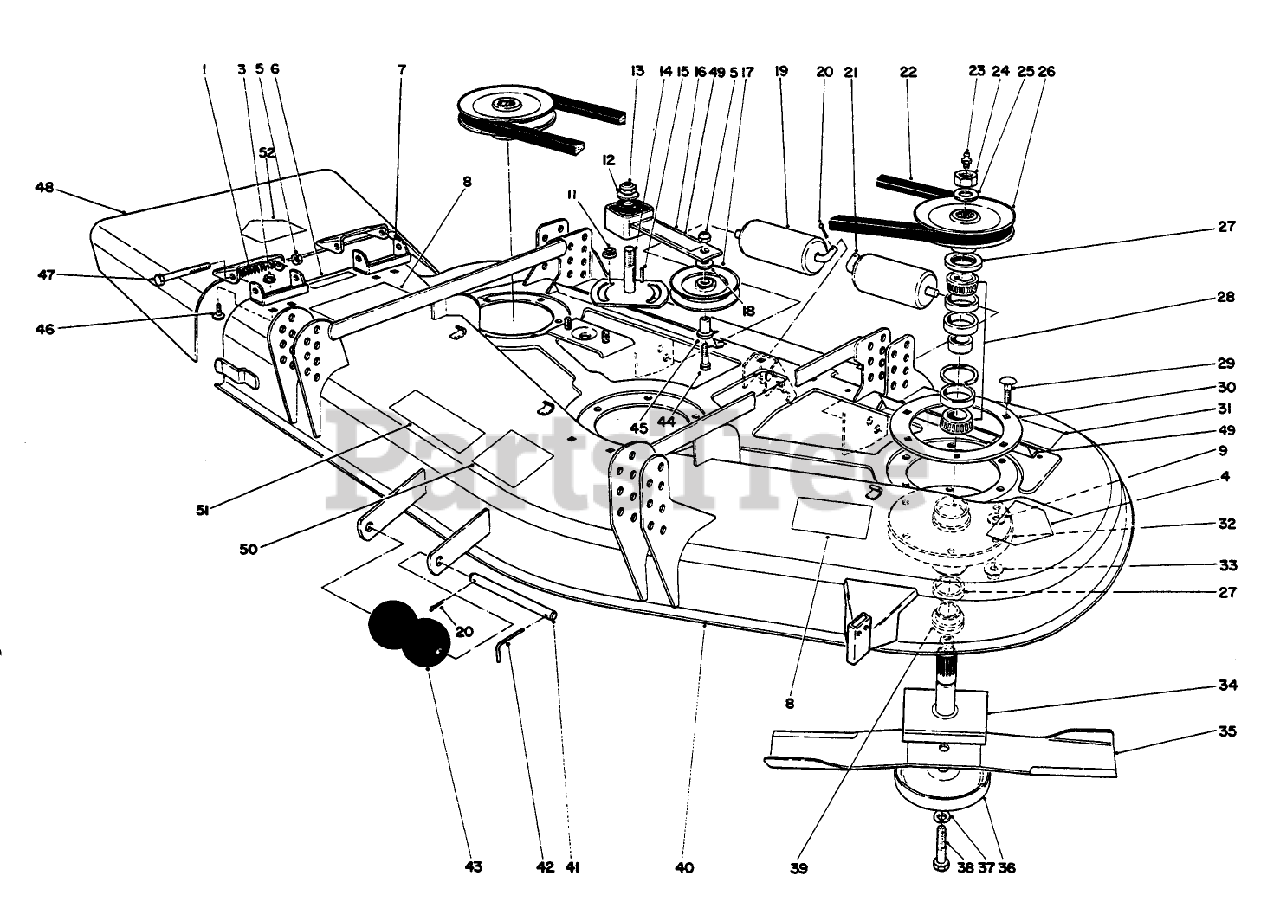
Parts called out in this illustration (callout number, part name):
1	SPRING
3	NUT-HF
4	DECAL-DANGER
5	NUT-HEX
6	DECAL-DANGER
7	Bracket-Pivot
8	DECAL-DANGER, THROWN OBJECT
9	WASHER-FLAT
11	NUT-HHF, WHIZ
12	WASHER-FLAT
13	NUT-LOCK, NI
14	PLATE-IDLER
15	KEY-SQUARE
16	IDLER ARM ASM
17	PULLEY-IDLER
18	WASHER-FLAT
19	ROLLER-DECK
20	PIN-COTTER
21	SHAFT-ROLLER, REAR
22	V-BELT
23	FITTING-GREASE
24	NUT-HEX
25	WASHER
26	BEARING ASM
27	SEAL-OIL
28	BEARING ASM
29	SCREW-CARR
30	SUPPORT-DECK, RING
31	DECAL-TORQUE
32	HOUSING-SPINDLE
33	NUT-HF
34	SHAFT
35	Blade
36	CUP-SCALP, ANTI
37	WASHER-LOCK
38	SCREW-BLADE
39	SPACER
40	Cutting Deck
41	SHAFT-ROLLER
42	PIN-SPECIAL
43	ROLLER
44	SCREW-HH
45	BUSHING-PULLEY
46	SCREW-CARR
47	SCREW-HH
48	Deflector-Grass (Incl. Ref. #4)
49	DECAL-DANGER
50	DECAL
51	DECAL-PROLINE
52	DECAL-DANGER
